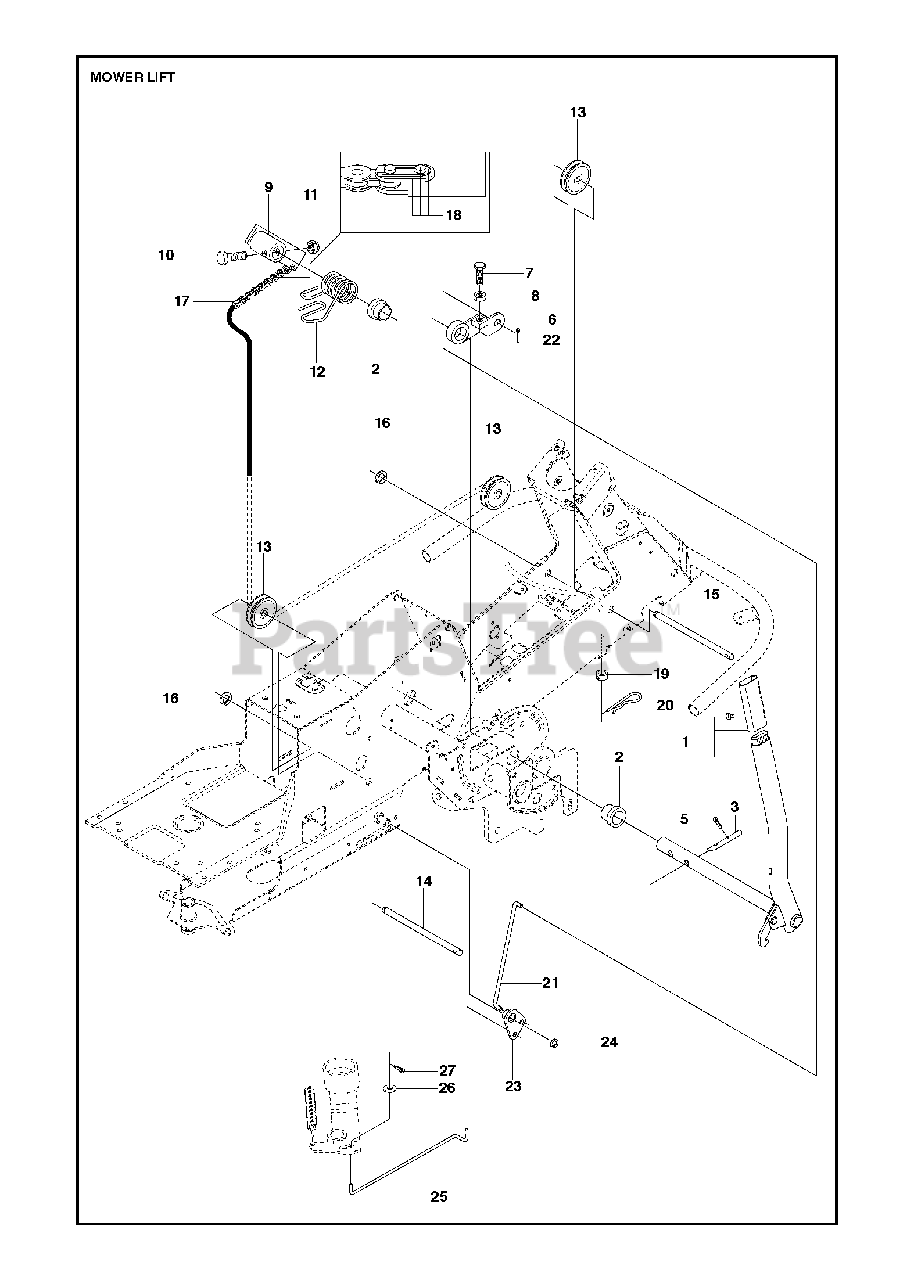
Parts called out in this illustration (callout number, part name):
1	LIFTING LEVER ASSY
2	BUSH
5	SPLIT PIN
6	LEVER CLUTCH
9	LIFTING ARM
16	LOCK RING
21	CONNECTION ROD
22	SPLIT PIN
24	RETAINING RING
25	CONNECTION ROD
27	SPLIT PIN
